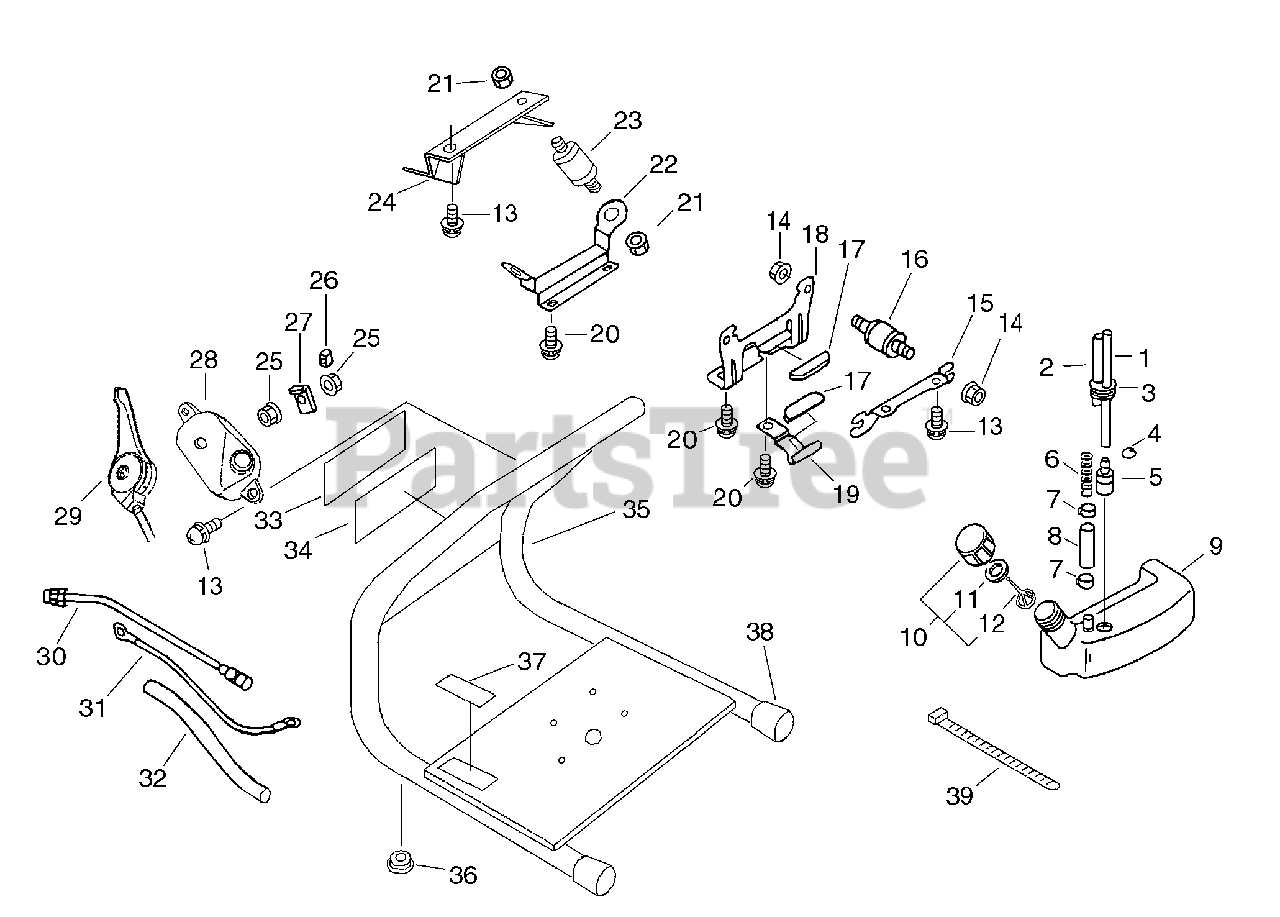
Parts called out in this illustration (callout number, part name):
1	PIPE, FUEL 3×6×200
2	PIPE, FUEL 3×6×100
3	GROMMET, FUEL
4	CLIP Ø6.5 MM
5	FILTER, FUEL
6	SPRING, COMPRESSION
7	CLIP 10.5 MM
8	PIPE, FUEL
9	TANK, FUEL
10	CAP ASSY, FUEL
11	GASKET, FUEL CAP
12	CONNECTOR, CAP L= 100 MM
13	SCREW 5×12
14	NUT, FLANGE
15	BRACKET, ENGINE
17	CUSHION, FUEL TANK
18	BRACKET, FUEL TANK
19	BRACKET, FUEL TANK
20	SCREW 6×14
22	PLATE, ANGLE
24	PLATE, ANGLE
25	NUT M5
27	PLATE, FIXED
28	BRACKET, THROTTLE
29	CONTROL, THROTTLE
30	SWITCH, STOP
33	LABEL - ECHO
34	LABEL, MODEL
36	GROMMET
37	LABEL - CAUTION
38	CAP, CUSHION
39	STRAP, TIE
